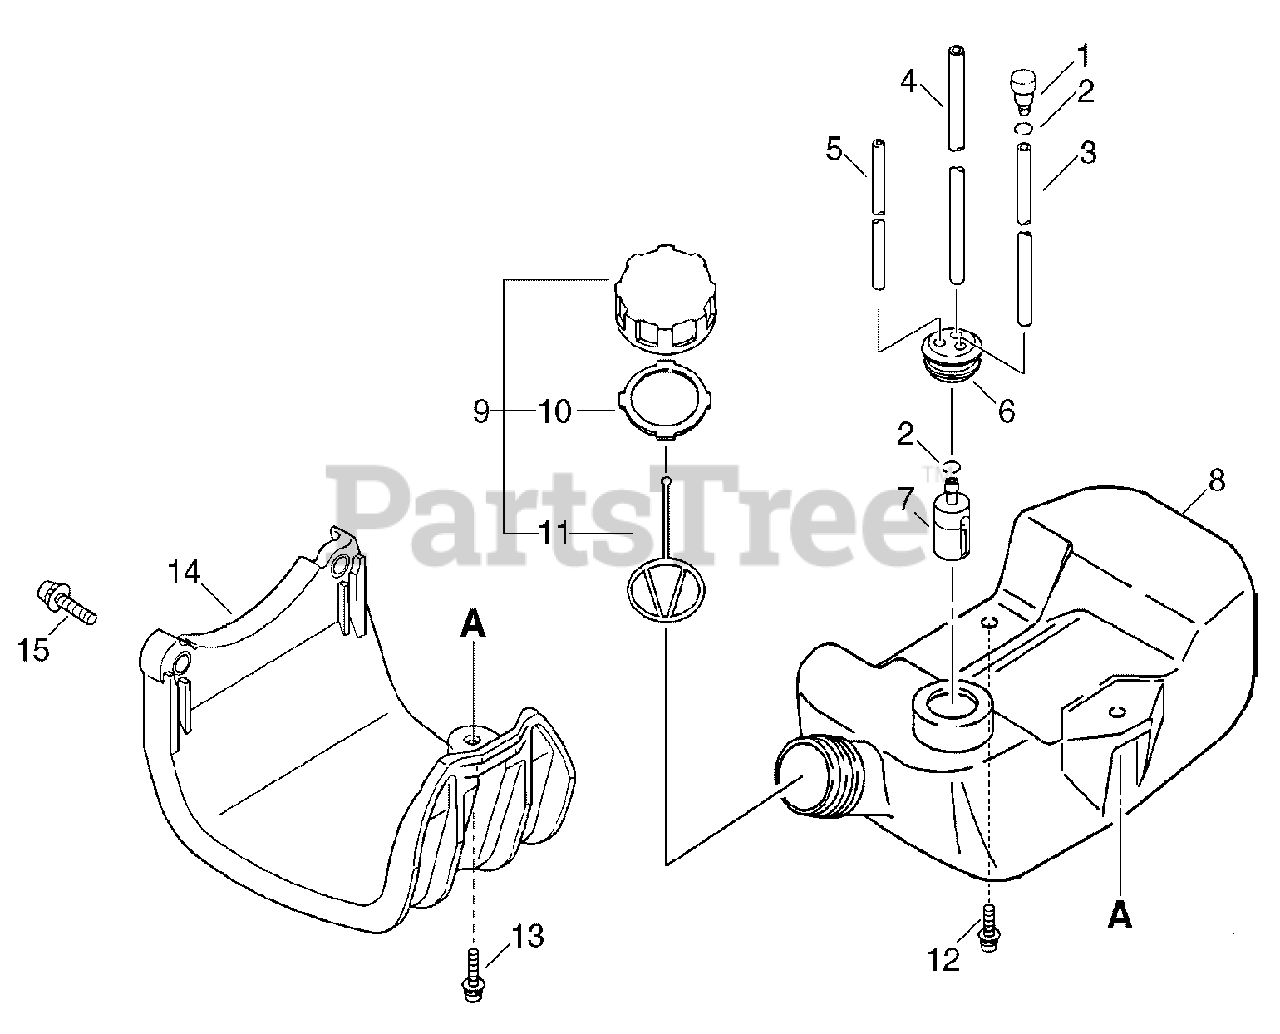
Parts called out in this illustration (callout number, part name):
1	VENT, FUEL TANK
2	CLIP - 6.5
3	PIPE - 3X6X100 -- BLACK
4	PIPE - 3X6X170 -- BLACK
5	PIPE - 3X6X60 -- CLEAR
6	GROMMET
7	FILTER, FUEL
8	TANK, FUEL
9	CAP ASSY - ORANGE
10	GASKET, CAP
11	CONNECTOR, CAP
12	SCREW - 5X16
13	SCREW - 5X20
14	GUARD, FUEL TANK
15	SCREW - 5X22
